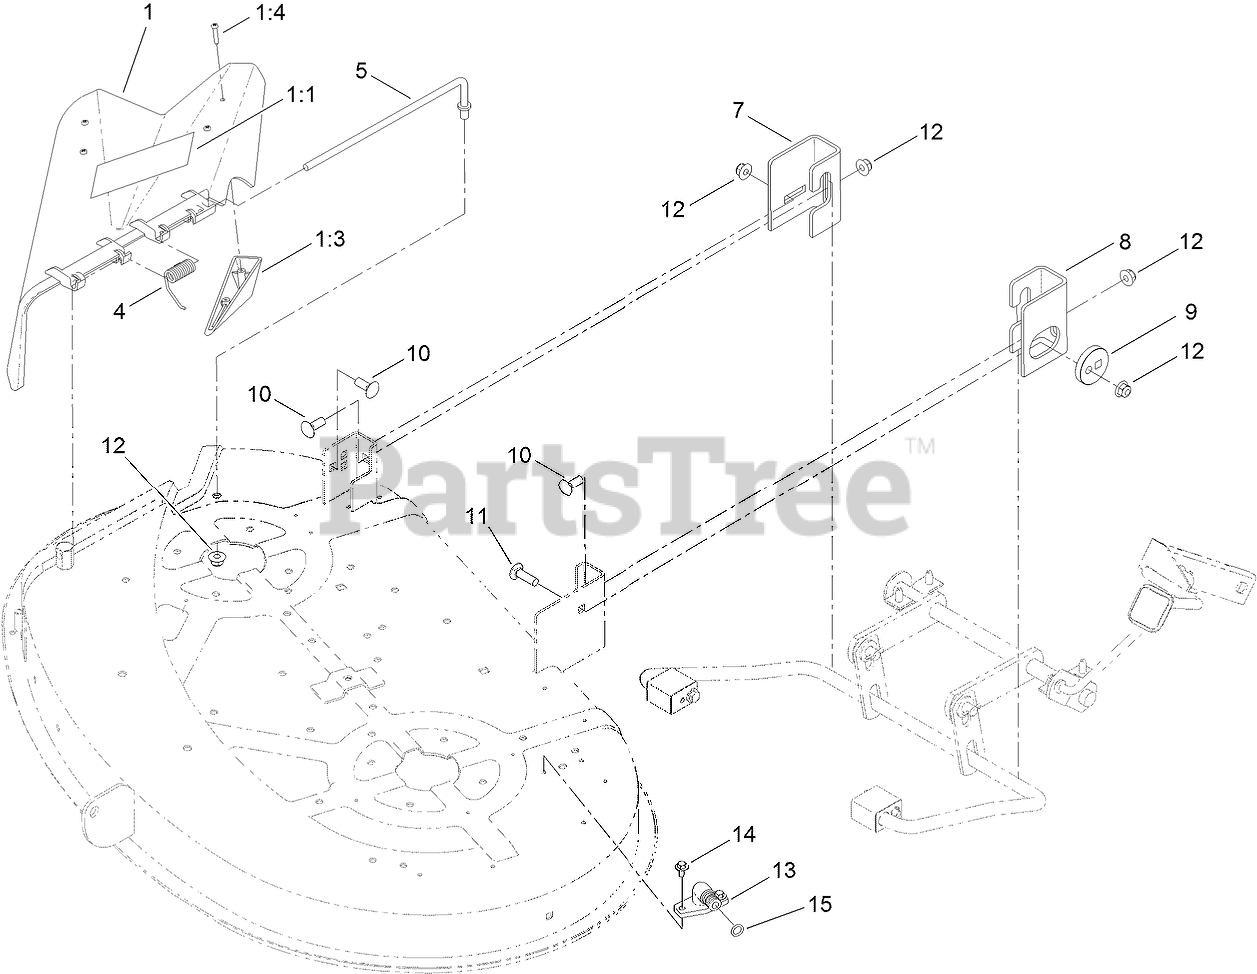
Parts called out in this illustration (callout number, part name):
1	DEFLECTOR ASM
1:1	DECAL-DANGER
1:3	KICKER
1:4	SCREW-PPH
4	SPRING-TORSION
5	ROD-PIVOT
7	BRACKET-HANGER, RIGHT REAR
8	BRACKET-HANGER, LEFT REAR
9	ECCENTRIC
10	BOLT-CARR
11	SCREW-CARR
12	NUT-HF, NI
13	FITTING-WASHOUT
14	SCREW-HHFTF
15	O-RING
